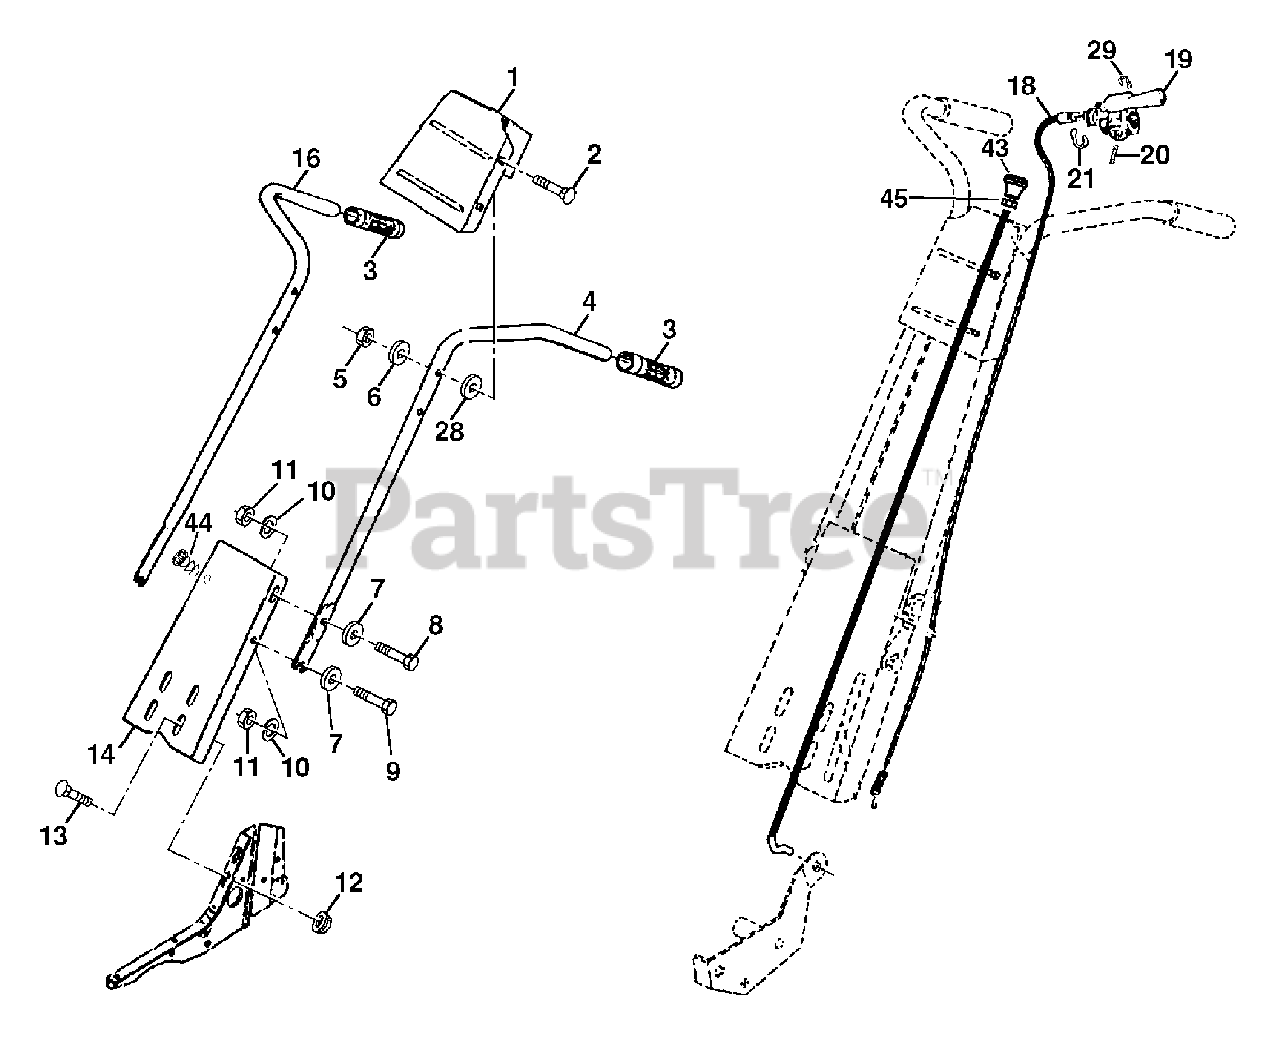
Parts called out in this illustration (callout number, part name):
1	Panel Pnt Control
2	Bolt, Carriage 5/16-18 UNC x 1-1/2
3	Grip, Handle
4	Handle, L.H.
5	Locknut, Crown 5/16-18
6	Washer 11/32 x 11/16 x 16 Ga.
7	Washer 3/8 x 7/8 x 14 Ga.
8	Bolt, Hex Hd. 5/16-18 x 1
9	Bolt, Hex Hd 5/16-18 x 3/4
10	Washer, Lock 5/16
11	Nut, Hex 5/16-18
12	Nut, Flanged 5/16-18
13	Bolt, Carriage 5/16-18 x 3/4 Gr. 5
16	Handle, R.H.
18	Cable, Control, Tine
19	Lever, Control, Tine
20	Pin, Pivot
21	Ring, Klip
28	Washer 13/32 x 13/16 x 12 Ga.
29	Retaining, Ring
43	Cable Assembly, Reverse
44	Clip
45	Nut Keps 3/8-24 Unf
